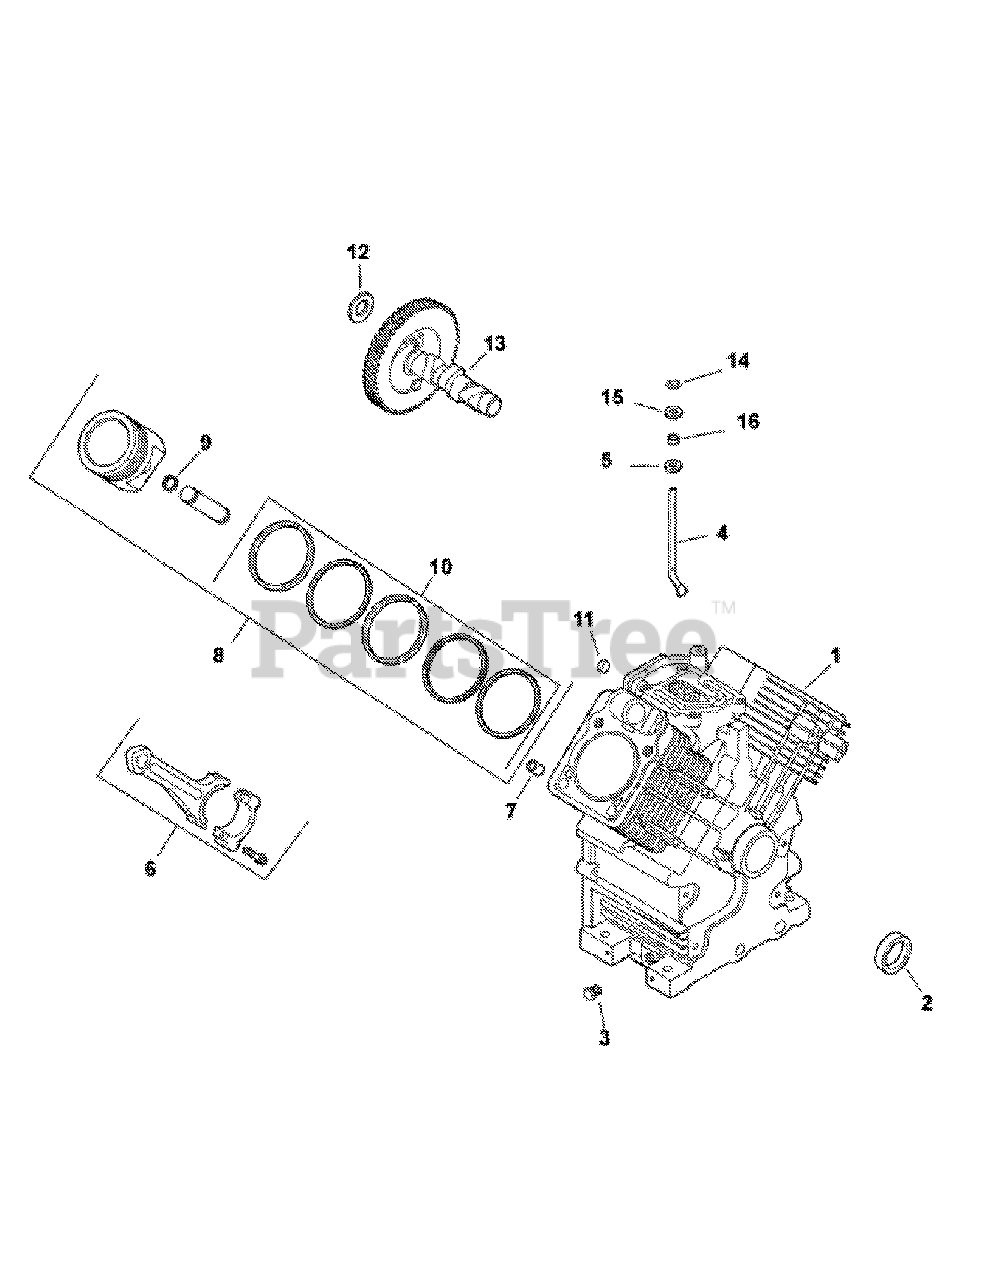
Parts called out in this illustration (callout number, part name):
1	Crankcase Use: Short Block
2	Seal, Oil (Helix Lip) 1.78"Od & 1.26" Id
3	Plug, Sq Hd Pipe 3/8"
4	Shaft, Governor Cross
5	Washer, Flat 11/32"
6	Rod, Assembly Connecting
6	Rod, Assembly Connecting (.25 O.S.)
7	Pin, Locating
8	Kit,Piston Assy W/Ring 77Mm-Std (Inclludes 9 & 10)
8	Kit, Piston Assy W/Ring Set (.08)
8	Kit,Pstn Assy W/Rng St(0.25,77M)
8	Kit,Piston W/Ring St (0.5),77Mm
9	Retainer, Piston Pin
10	Ring Set (Std)
12	Shim, Camshaft (White .028")
12	Shim, Camshaft (Blue .03")
12	Shim, Camshaft (Red .032")
12	Shim, Camshaft (Yellow .034")
12	Shim, Camshaft (Green .036")
12	Shim, Camshaft (Gray .038")
12	Shim, Camshaft (Black .04")
13	Kit, Camshaft (Includes 12 422 08-S & 25 357 14-S)
14	Retainer, Ring
15	Washer, Flat 9 Mm
16	Seal, Governor Cross Shaft
